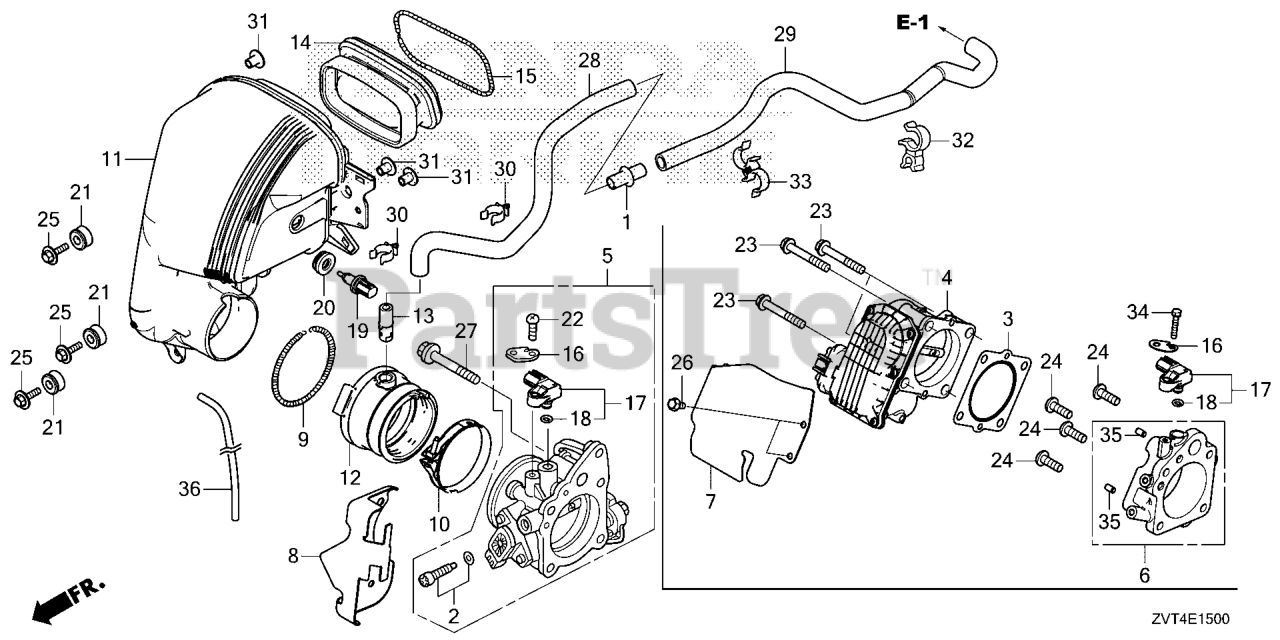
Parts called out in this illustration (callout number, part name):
1	JOINT, BRETHER TUBE
3	GASKET, THROT BODY
4	ELECTRONIC CONTL
6	SPACER COMP
7	GUARD, THROTTLE BODY
9	SPRING, AIR FLOW TUBE
10	BAND, AIR FLOW
11	CASE COMP, MUFFLER
12	GROMMET, MUFFLER
14	GROMMET, MUFFLER DUCT
15	SPRING, MUFFLER DUCT GROMMET
16	BRACKET, SENSOR WIRE
17	SENSOR ASSY., MAP
19	SENSOR ASSY., AIR TEMPERATURE
20	GROMMET, TA SENSOR
21	GROMMET, CASE (LOWER)
23	BOLT, FLANGE (8X55)
24	BOLT, SOCKET (8X25)
25	BOLT-WASHER (6X25)
26	BOLT, FLANGE (6X14)
28	TUBE, BREATHER A
29	TUBE B, BREATHER
30	CLAMP (18.5MM)
31	COLLAR (12X6.5)
32	CLAMP, FUEL HOSE
33	CLAMP, CANISTER DRAIN
34	SCREW, PAN (5X) (18)
35	PIN A, DOWEL (6X10)
36	BULK HOSE, VINYL (4X7X8000) (95003-07(95003-07001-60M) (CARBURETOR NO.)
